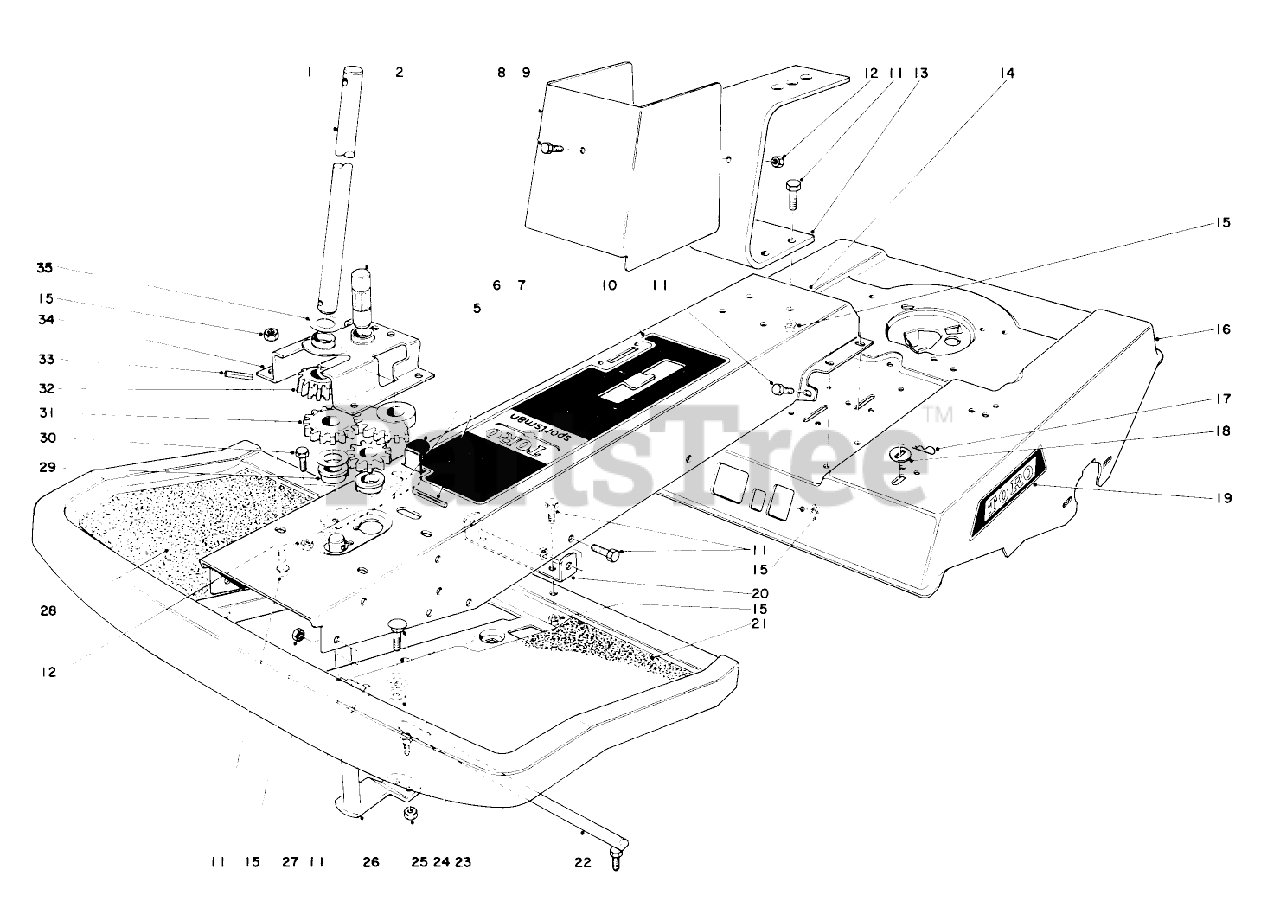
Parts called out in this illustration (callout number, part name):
5	Parking Brake Tip
6	Parking Brake Spring
8	SCREW-HH
9	Cover Seat
10	Decal (Model 56100)
11	SCREW-HH
13	Seat Spring
14	Center Frame
16	Frame
18	Washer
19	Decal
20	Support
21	Foot Pad L. H.
22	Ball Joint
23	SCREW-CARR
24	NUT-HF
27	Foot Rest
28	Foot Pad R. H.
30	SCREW-HH
33	PIN-ROLL, SLOTTED
35	Washer
